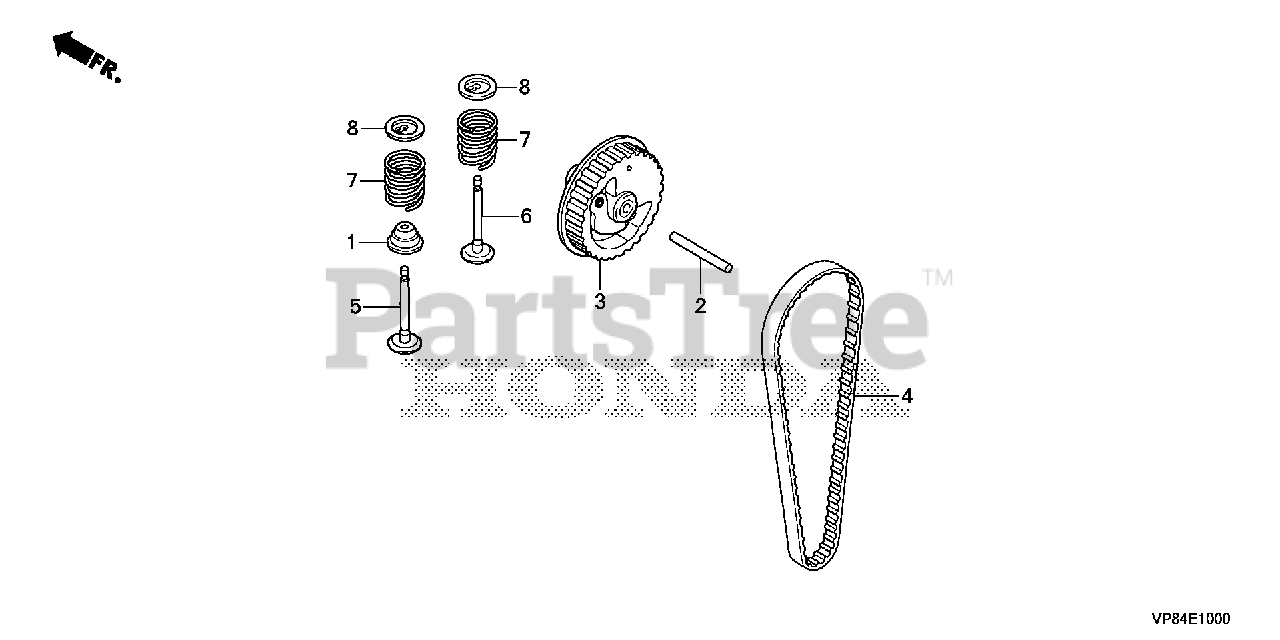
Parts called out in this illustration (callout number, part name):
1	SEAL, VALVE STEM
2	ROLLER (4X31.8)
3	PULLEY, CAMSHAFT
4	BELT, TIMING (76ZU5 G-310)
5	VALVE, IN. (FI)
6	VALVE, EX. (ZE)
6	VALVE, EX. (FE)
7	SPRING, VALVE
8	RETAINER, VALVE SPRING
